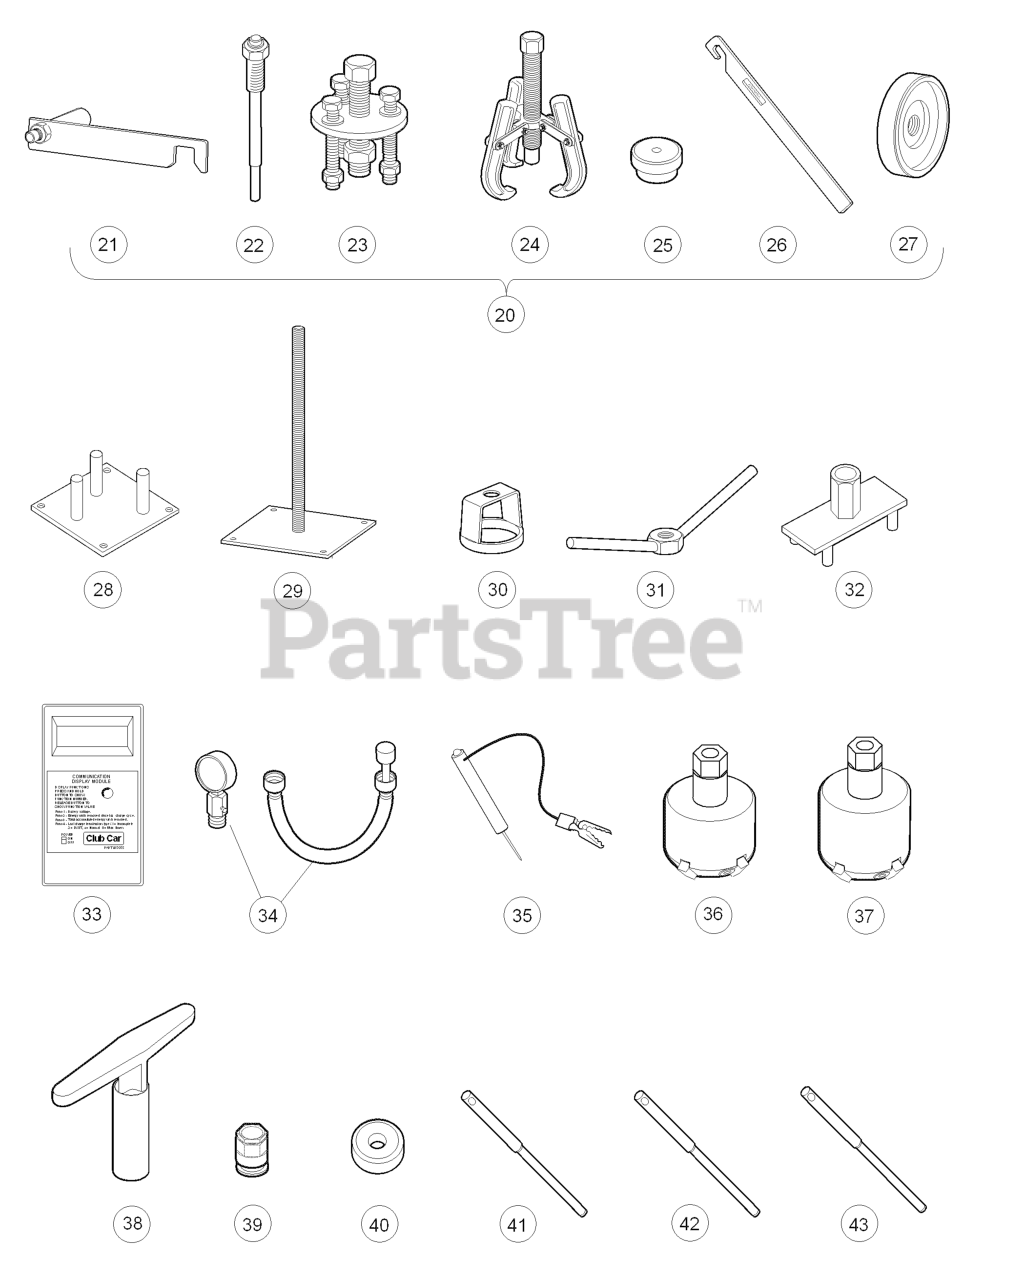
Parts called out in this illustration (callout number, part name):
20	C.C. CLUTCH TOOL KIT
21	TOOL, CLUTCH ALIGNMENT
22	TOOL, CLUTCH PULLER
23	CLUTCH DRIVE HUB PULLER
24	DRIVEN CLUTCH CAM PULLER
25	DRIVEN CLUTCH PULLER PLUG
26	DRIVE CLUTCH HOLDER TOOL ASM.
27	PRESS WELDMENT
28	TOOL-STATIONARY PRIMARY
29	TOOL-SPRING COMPRESSION BASE
30	TOOL-SPRING COMPRESSION COLAR
31	TOOL-SPRING COMPRESSION COLAR
32	TOOL-SPIDER PRIMARY
33	COMMUNICATION DISPLAY MODULE
34	COMPRESSION GUAGE AND ADAPTER
35	CONTINUITY TESTER
36	CUTTER, VALVE SEAT, #122
37	CUTTER, VALVE SEAT, #115
38	ADAPTER, T-WRENCH
39	ADAPTER, T-WRENCH
40	Cutter, Valve Seat, 60 Degree
41	PILOT, 6.6 MM
42	PILOT, 6.62 MM
43	PILOT, 6.65 MM
